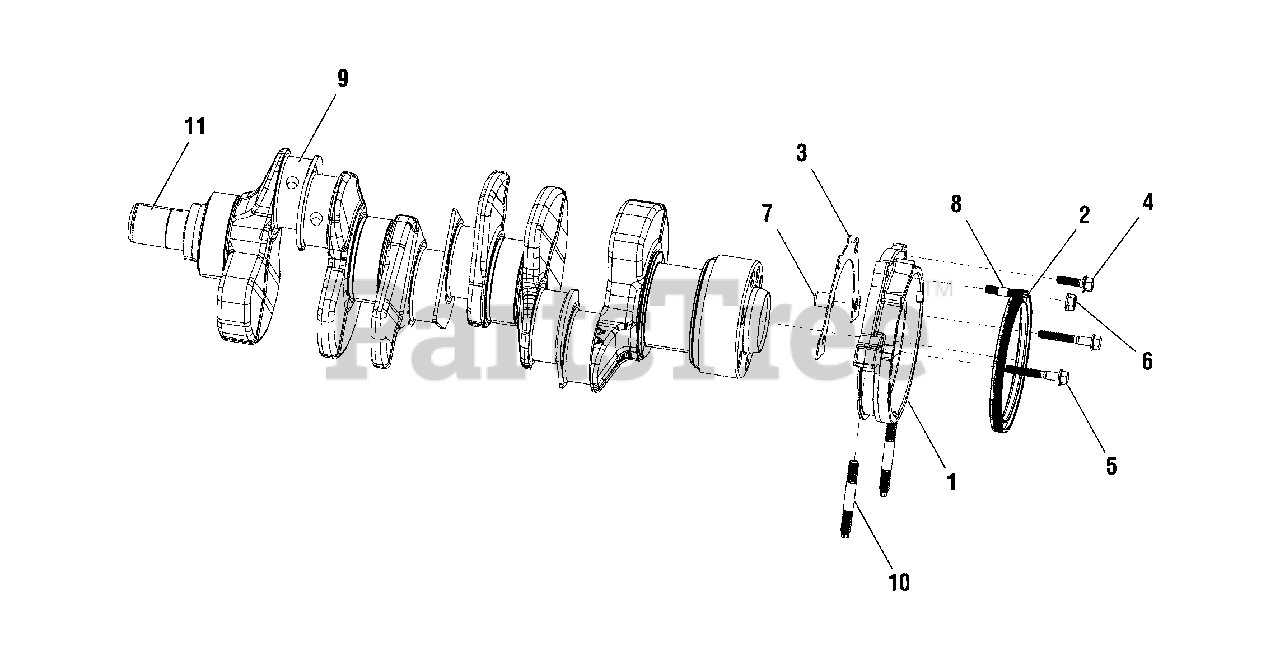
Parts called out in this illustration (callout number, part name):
1	HOUSING, CRK/SHF RR OIL SEAL
2	SEAL, REAR CRANKSHAFT
3	GASKET, CRK/SHF RR OIL SEAL HOUSING
4	BOLT, CRK/SHF RR OIL SEAL HOUSING
5	BOLT, CRK/SHF RR OIL SEAL HOUSING
6	NUT, CRK/SHF RR OIL SEAL RETAINER
7	PIN, CRK/SHF RR OIL SEAL HOUSING LOCATOR
8	STUD, CRK/SHF RR OIL SEAL RETAINER
9	SET, MAIN BEARING
10	STUD, CRK/SHF RR OIL SEAL RETAINER
11	CRANKSHAFT
